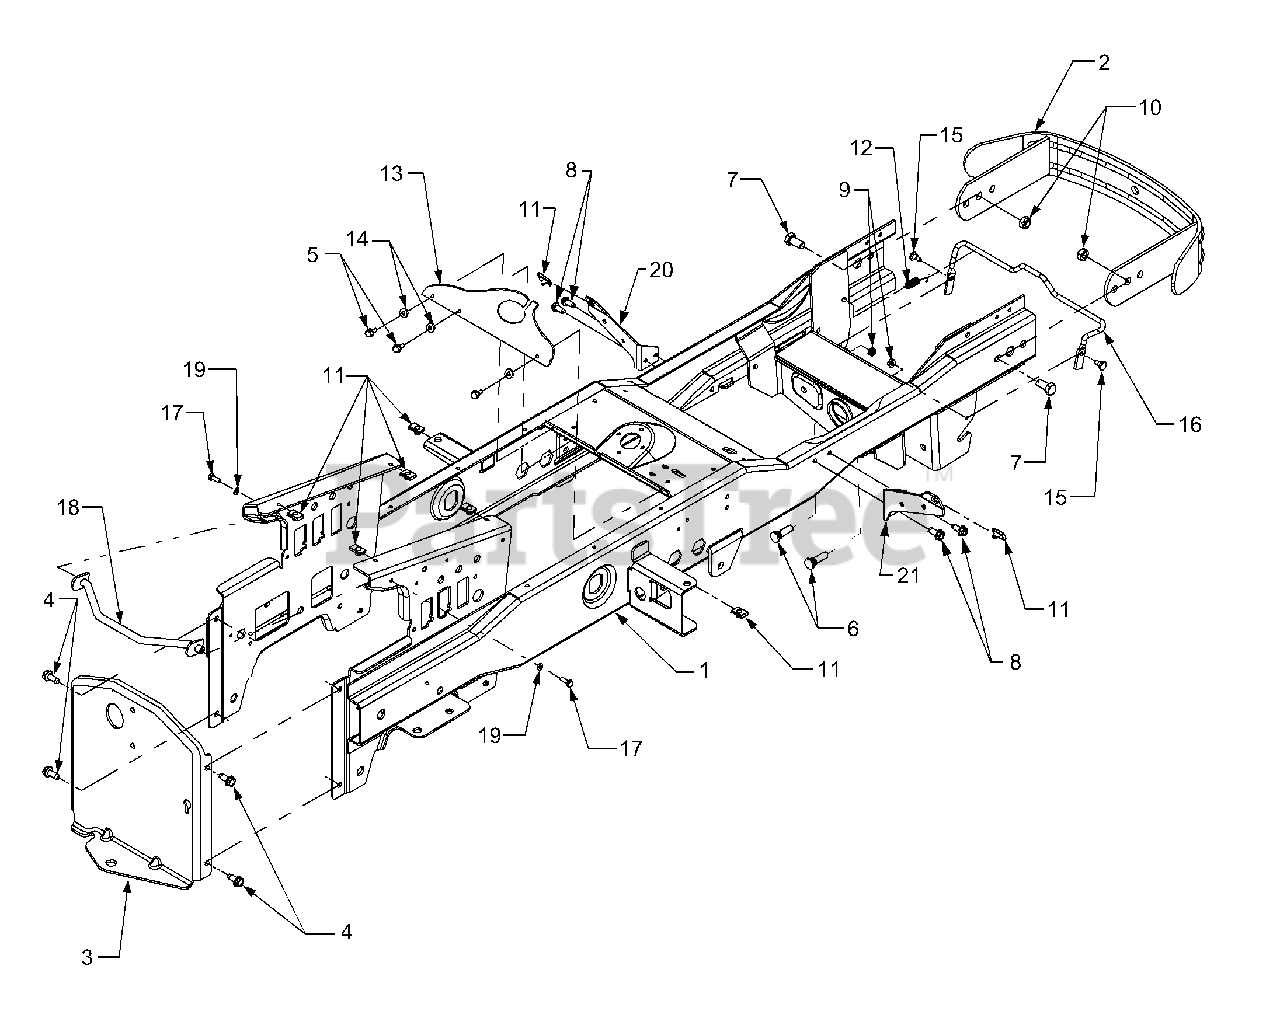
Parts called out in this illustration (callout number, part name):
1	Frame Assembly
2	Bumper, Front
4	Screw, Hex Wash. Hd. Tapp 3/8-16 x .75
5	Screw, Hex Wash. Hd. Tapp 1/4-20 x .5
6	Screw, Round Hd., 3/8-24
7	Screw, Hex Cap 1/2-13 x 1.0 GR5
8	Screw, Hex Wash. Hd. Tapp 5/16-18 x .75
9	Nut, Hex Flange Lock, 1/4-20
10	Nut, Hex Lock, 1/2-13
11	Speed Nut, U-Type, 5/16-18
12	Spring, Extension
13	Flap, Intk.
14	Washer, Flat, .283 x .75 x .030
15	Shoulder Screw, .312 x .18
16	Rod, Front Latch
17	Screw, Hex Cap, 1/4-20 x .75 GR5
18	Shaft, Tank Constraint
19	Washer, Lock, 1/4
20	Bracket, Running Board LH
21	Bracket, Running Board RH
